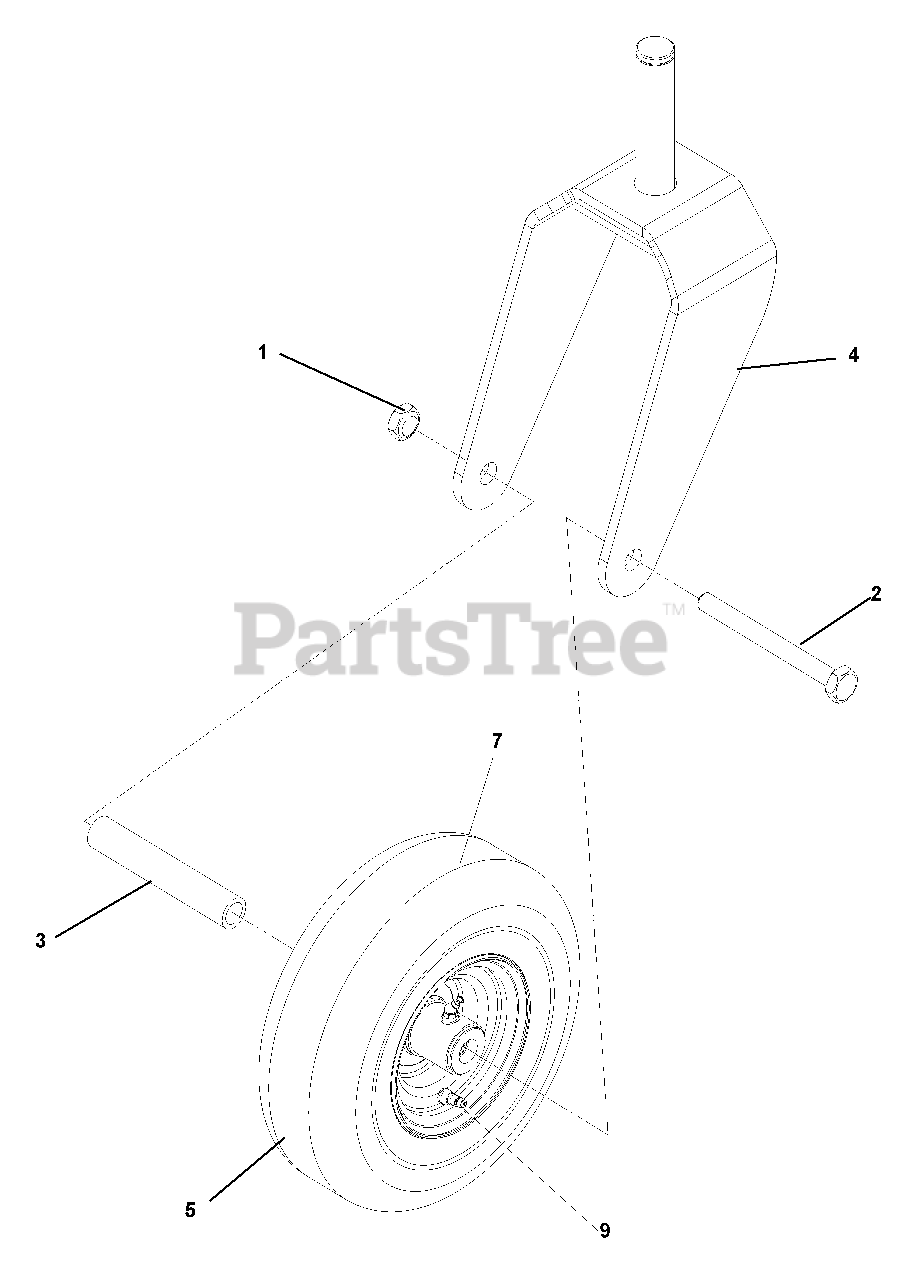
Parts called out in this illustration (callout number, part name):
1	NUT, 1/2-13, HEX NYLOC RING
2	HCS 1/2-13 X 5 1/2
4	CASTER
5	TIRE, COMPLETE
7	TIRE
9	VALVE STEM
